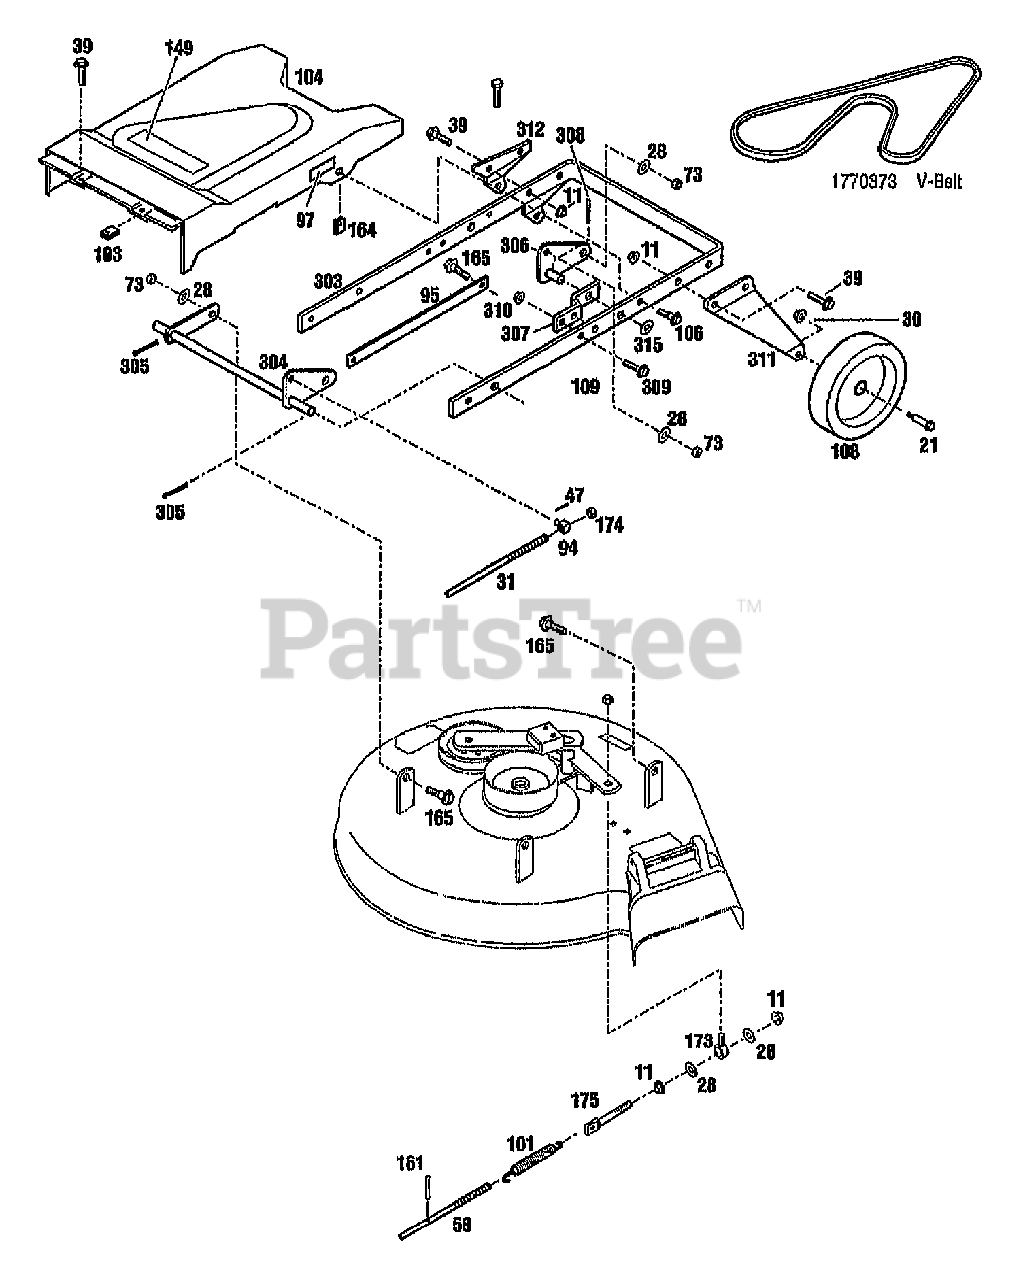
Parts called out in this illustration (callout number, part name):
11	NUT-HFLK 3/8-16 ZP
21	SCR-SHLDR 3/8-16
28	WASHER-FLAT 3/8 SAE
30	NUT-LOCK 3/8-16
31	ASSM-CRANK LIFT
39	SCR-HFLK 3/8-16X1.00 ZP
47	PIN-COTTER .125 X .75 ZP
58	ROD-LOWER BLADE
64	NUT-HFLK 5/16-18 ZP
73	NUT-HEX/JAM 3/8-16 ZP
94	BLOCK-PIVOT ZP
95	BAR-LEVELER
97	DECAL-CUTTING HEIGHT
101	SPRING
103	CLIP-J TYPE
104	COVER-BELT
106	SCR-HFLK 1/4-20X.75 G5 ZP
108	ASSM-TIRE & WHEEL
149	DECAL-LOGO TROY BILT
158	BELT-V
161	PIN-ROLL 1/8 X 3/4
164	NUT-SPEED
165	SCR-SHLDR 3/8-16X.25 G5ZP
173	BOLT-EYE
174	NUT-TOPLK .4375-14
175	BOLT-SPADE
303	FRAME-FRONT 26" {34068,34069}
303	FRAME-FRONT 22" {34067,34066}
304	ASSM-REAR LIFT
305	PIN-COTTER .120X1.25 ZP
306	ASSM-DECK LIFT
307	BRACKET
308	PIN-DRIVE .25X3.0 ZP
309	SCR-LOCK
310	NUT-HFLK 5/16-18 ZP
311	SUPPORT (RH)
312	SUPPORT (LH)
315	WASHER-1.305X.649X.098 ZP
